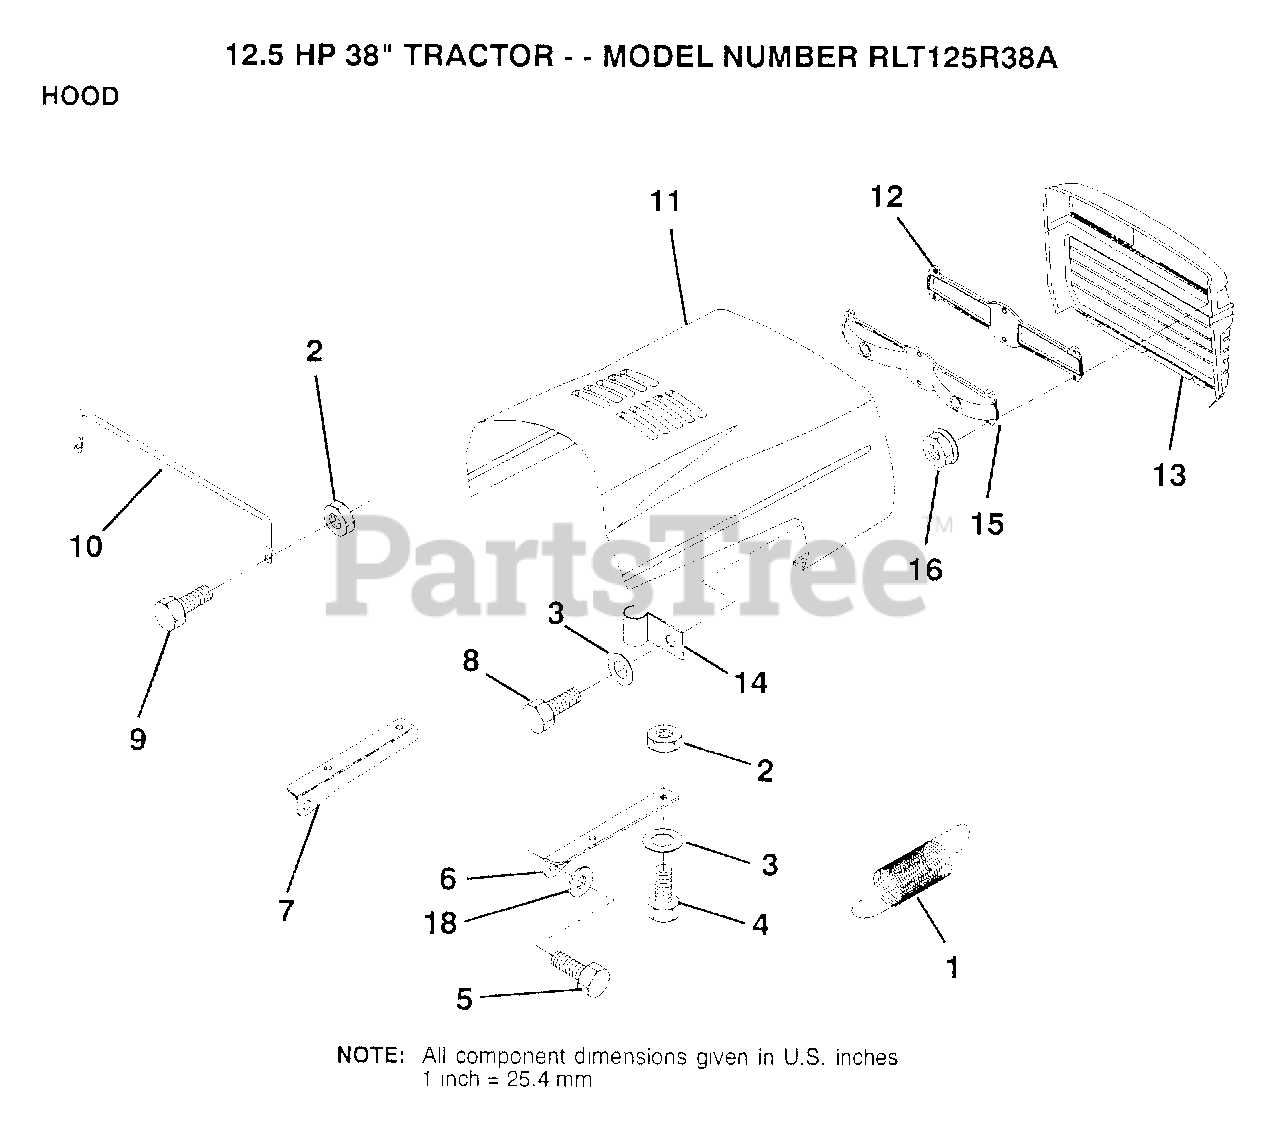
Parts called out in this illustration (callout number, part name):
1	EXT SPRING
2	NUT
3	WASHER
4	BOLT
6	BRKT HOOD RH
7	BRKT HOOD LH
10	"BRACE,HOOD"
14	CLIP T
18	WASHER
